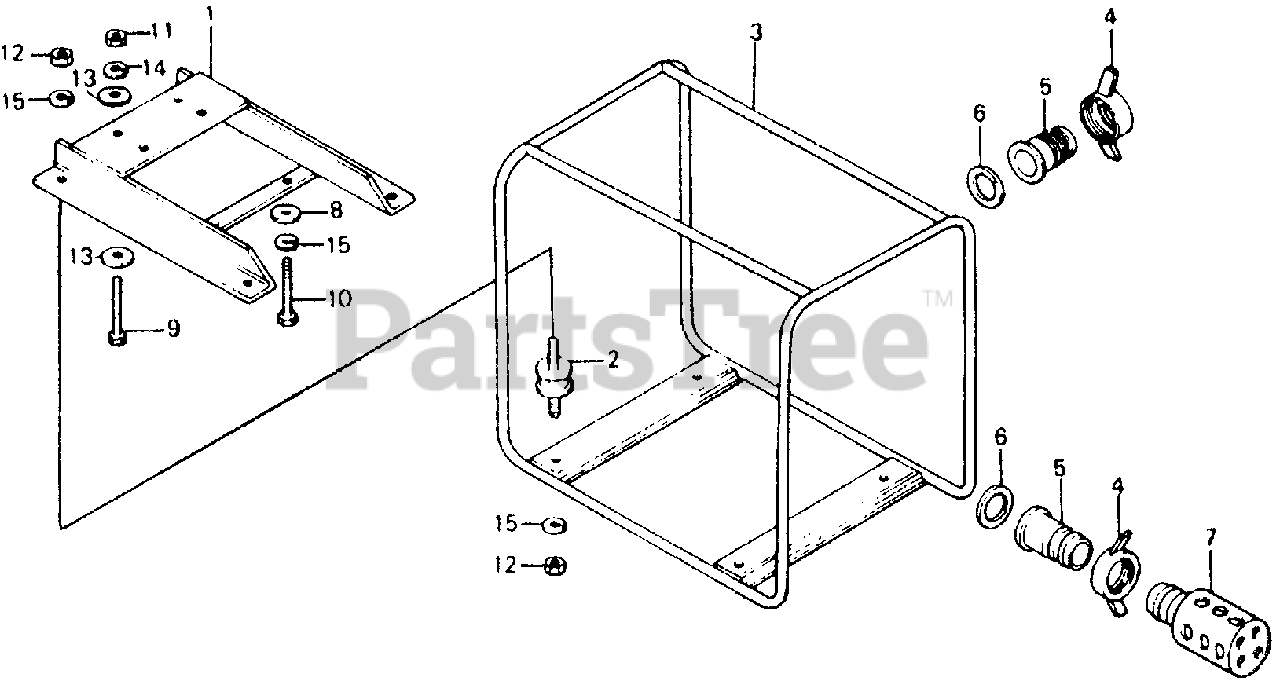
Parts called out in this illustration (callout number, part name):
1	BASE, ENGINE
2	RUBBER, CUSHION (NOT AVAILABLE)
3	PIPE, BASE
4	COUPLING, HOSE
5	JOINT, SUCTION
6	GASKET, HOSE COUPLING
7	STRAINER (NOT AVAILABLE)
9	BOLT, HEX. (10X50)
10	BOLT, HEX. (10X25)
11	NUT, HEX. (10MM)
12	NUT, HEX. (10MM)
13	WASHER, PLAIN (10MM)
14	WASHER, SPRING (8MM)
15	WASHER, SPRING (8MM)
